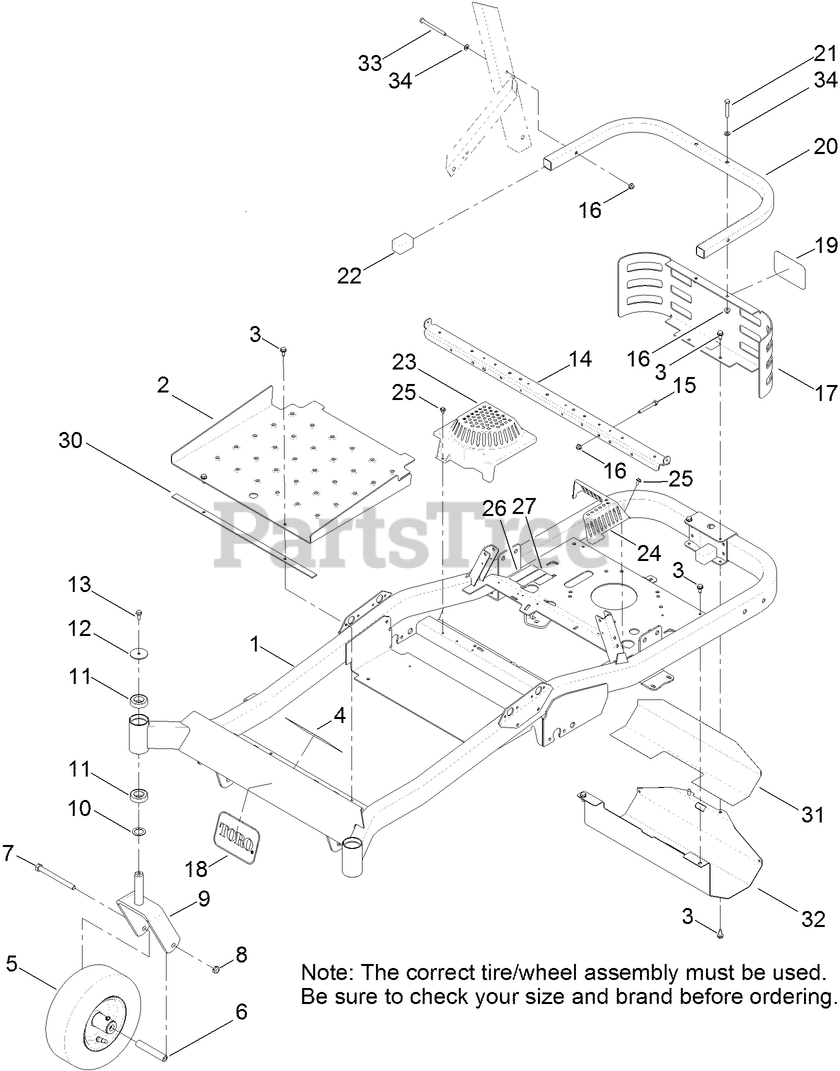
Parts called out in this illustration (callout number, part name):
2	PAN-FLOOR
3	SCREW-HWHTF
4	DECAL-SAFETY
5	TIRE AND WHEEL ASM (C S T)
5	TIRE AND WHEEL ASM (KENDA)
6	BUSHING-SPANNER
7	SCREW-HH
8	NUT-HEX
9	CASTER FORK ASM
10	WASHER-THRUST
11	BEARING-BALL
12	WASHER
13	SCREW-HHF
14	SUPPORT-SEAT
15	SCREW-HH
16	NUT-HF, NI
17	GUARD-REAR
18	DECAL
20	TUBE-GUARD
21	SCREW-HH
23	COVER-FAN, RH
24	COVER-FAN, LH
25	SCREW-HHFTF
26	DECAL-SERIAL
27	DECAL-EMISSIONS, E P A
30	STRIP-VIBRATION, ANTI
31	FOIL-HEAT SHIELD
33	SCREW-HH
34	WASHER-PLAIN
